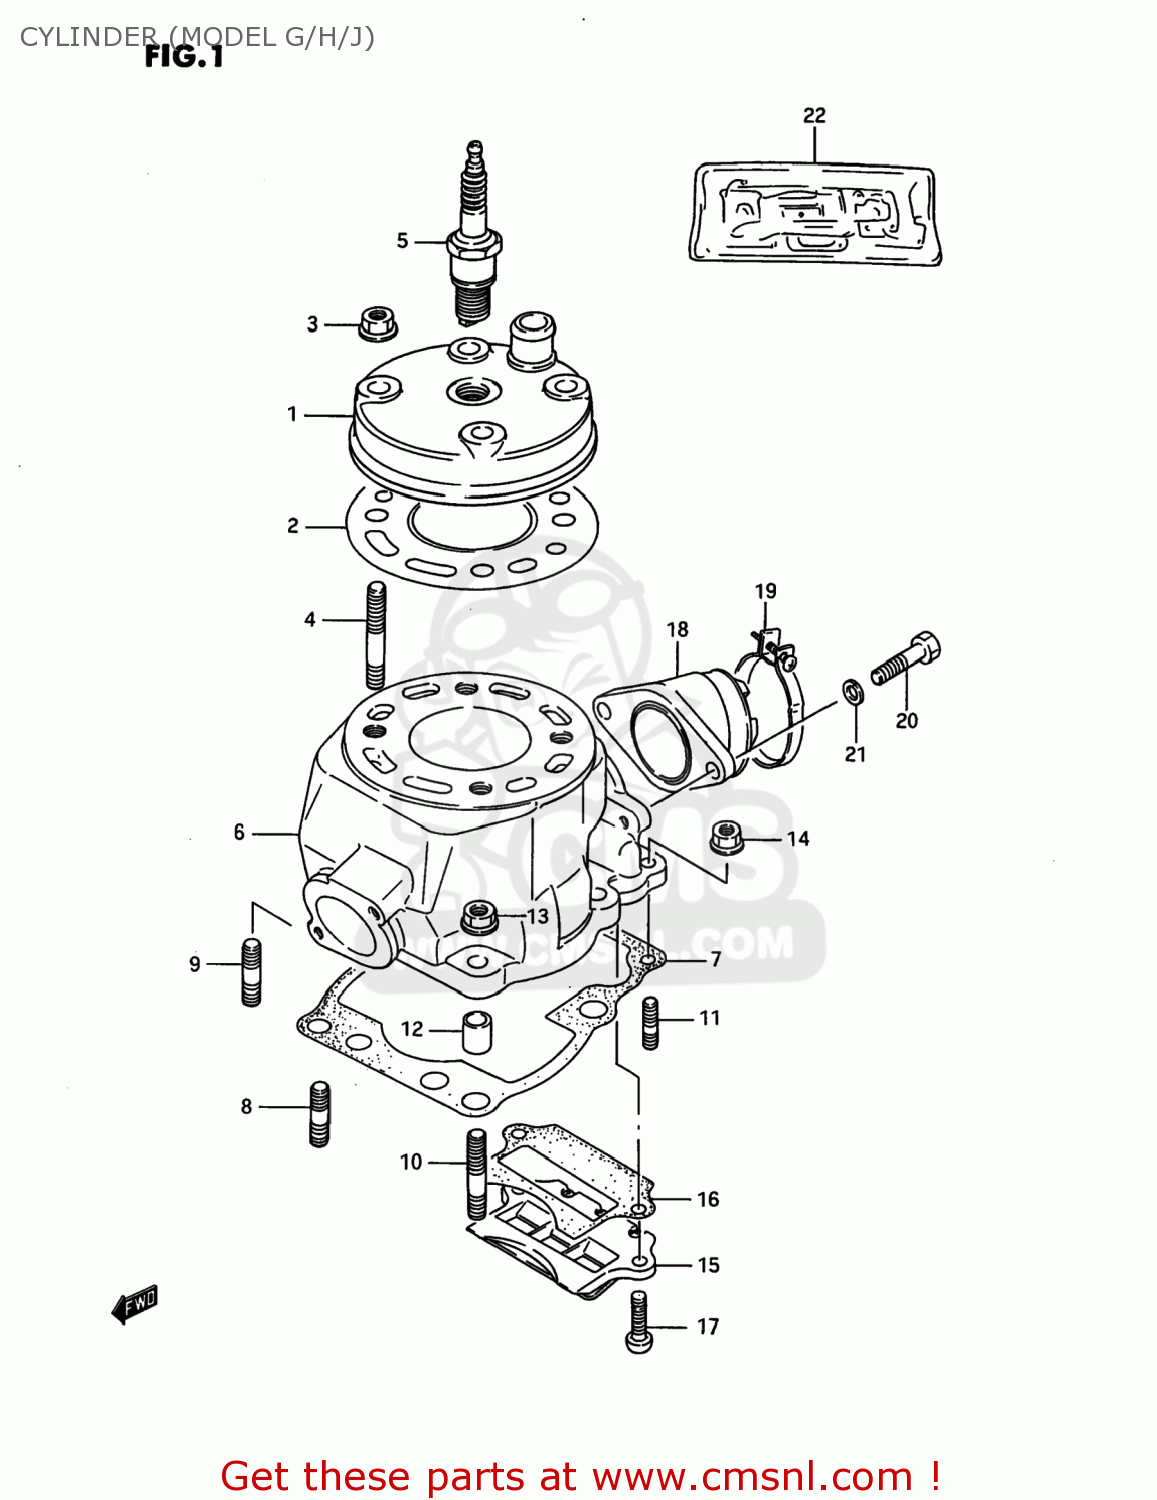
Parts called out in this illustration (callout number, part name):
1	HEAD,CYLINDER
2	GASKET,CYLINDER HEAD (MCA)
3	NUT
4	BOLT,STUD
5	SPARK PLUG B9ES
6	CYLINDER
7	GASKET,CYLINDER (MCA)
8	BOLT,STUD
9	STUD 8X20
10	STUD
11	STUD 6X16
12	PIN
13	NUT
14	NUT
15	VALVE ASSEMBLY,REED
16	GASKET,REED VALVE (NAS)
17	SCREW
18	PIPE,INTAKE
19	CLAMP
20	BOLT
21	WASHER,LOCK
22	GASKET SET (NAS)
